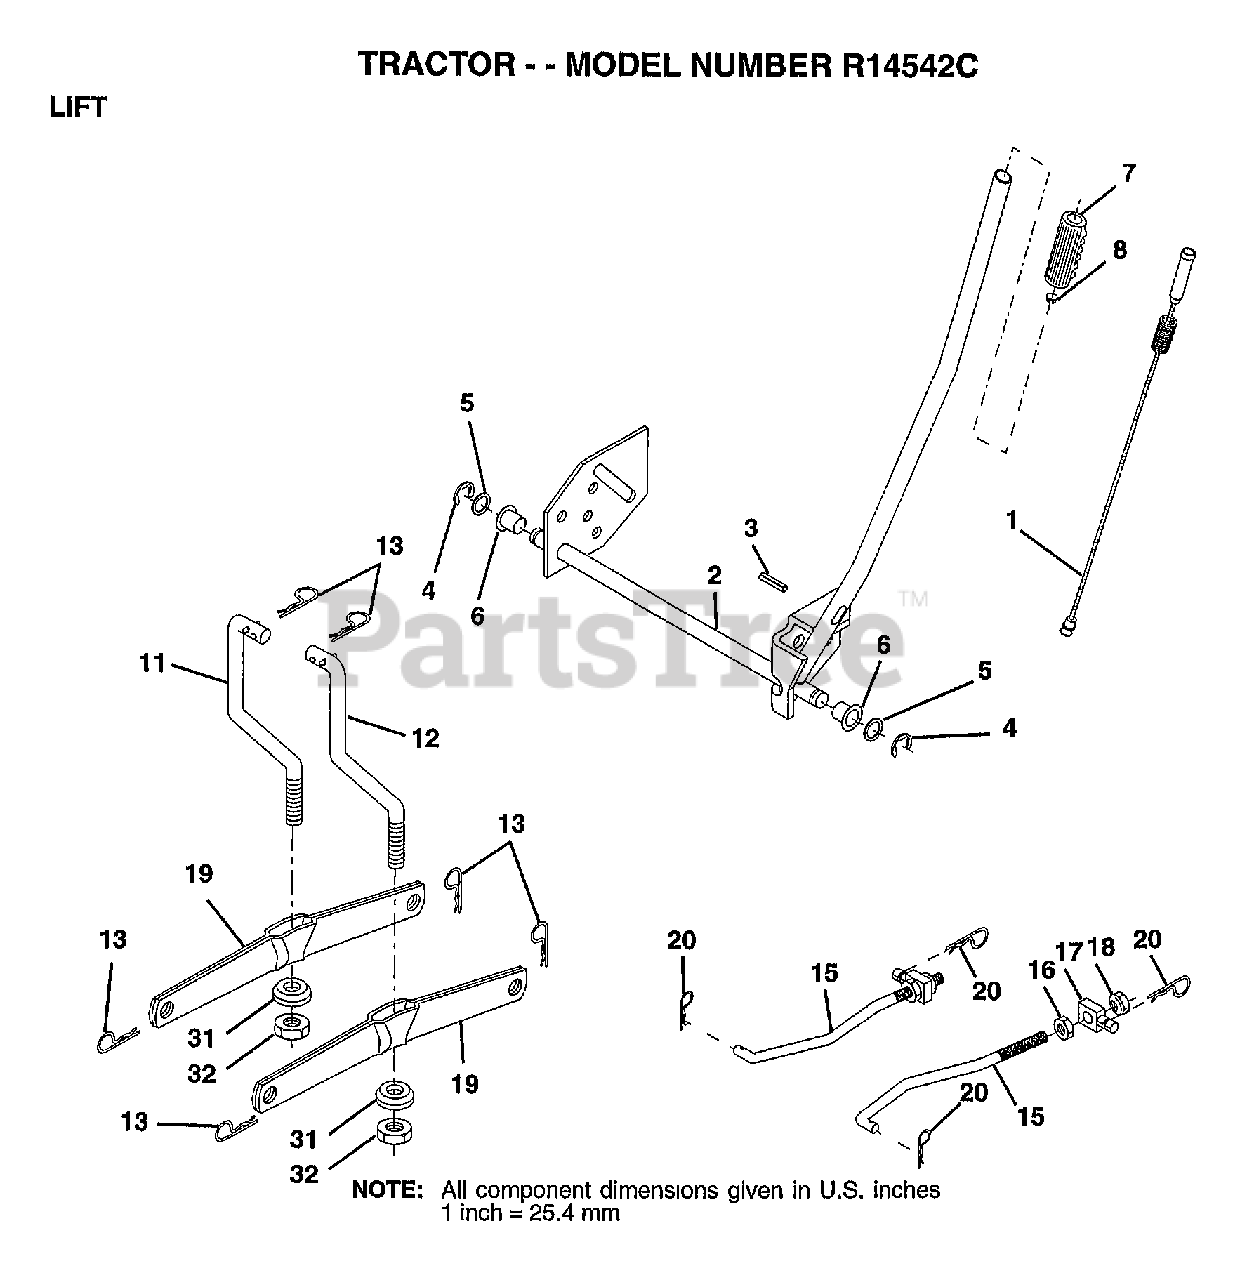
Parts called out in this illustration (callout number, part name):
1	WIRE.ASM.INNER.SP
2	"SHAFT AMS LIFT,RH"
3	PIN GROOVE
5	WASHER
6	NYLON BEARING
7	GRIP
15	LINK.FRONT
16	NUT
17	TRUNION
18	NUT.LK.W/WSH.1/2.
19	ARM SUSP REAR
20	RETAINER.SPRING
31	BEARING PVT LH
32	NUT.CROWNLOCK.3/8
